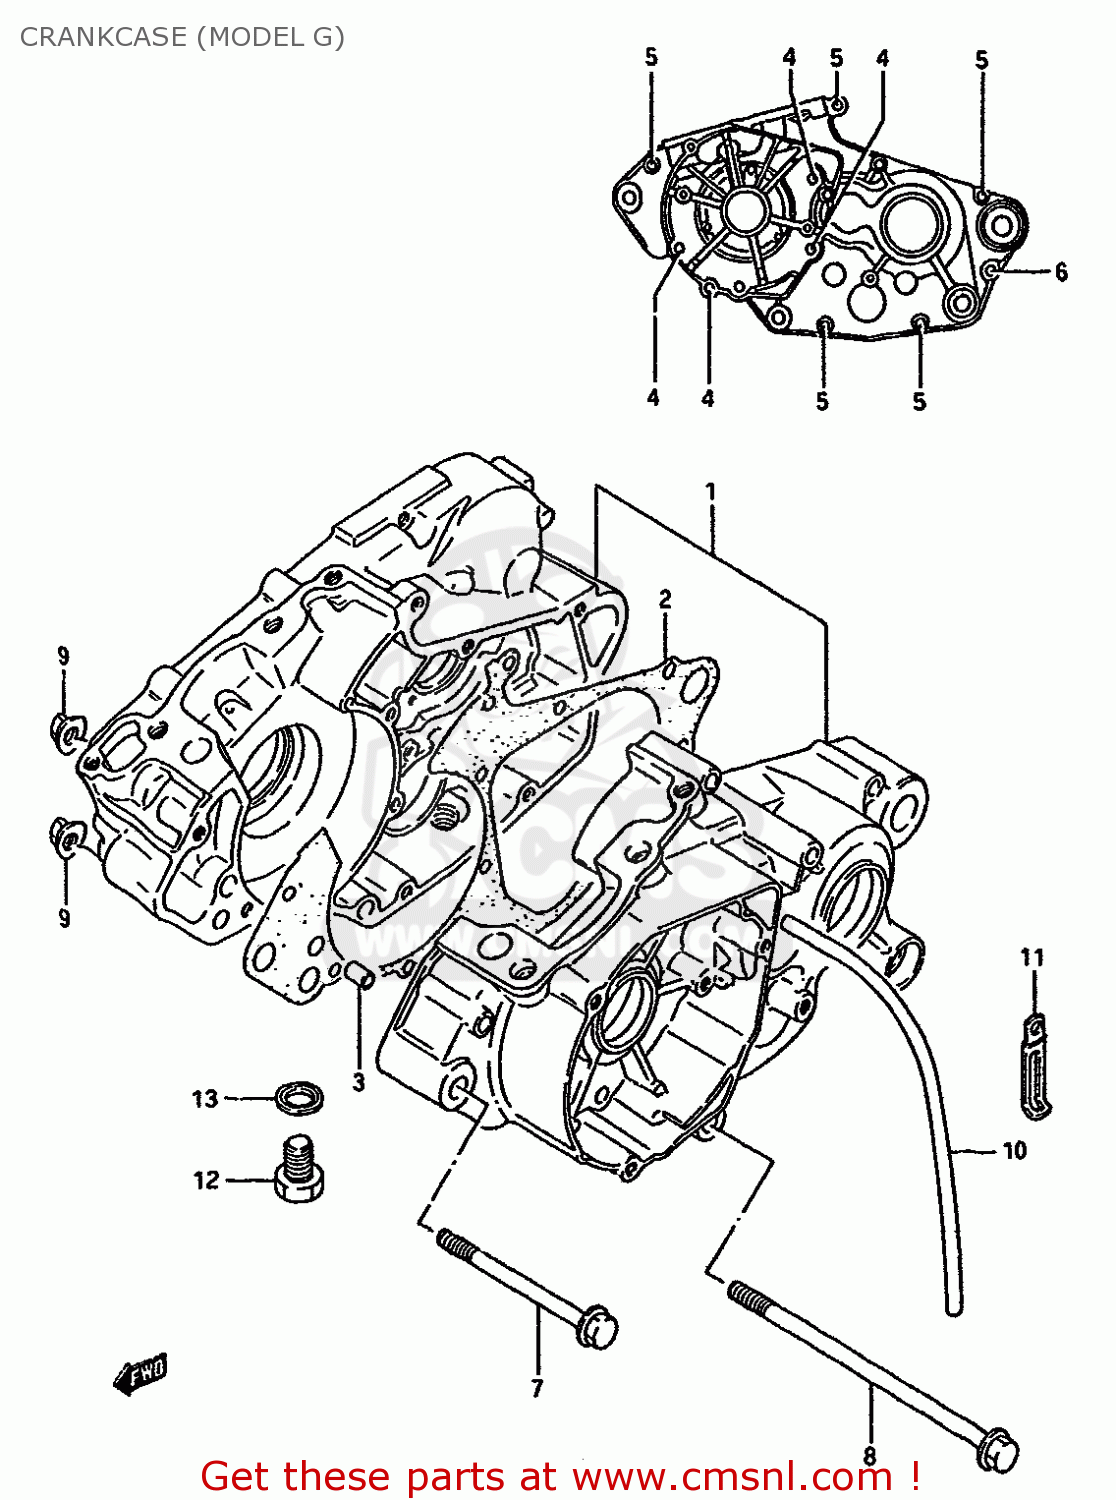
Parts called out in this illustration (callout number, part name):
1	CRANKCASE SET
2	GASKET,CRANKCASE (MCA)
3	PIN
4	SCREW
5	SCREW
6	SCREW 6X60
7	BOLT(8X95)
8	BOLT(8X150)
9	NUT
10	HOSE
11	CLAMP
12	PLUG
13	GASKET(14X19.2X2) (NAS)
